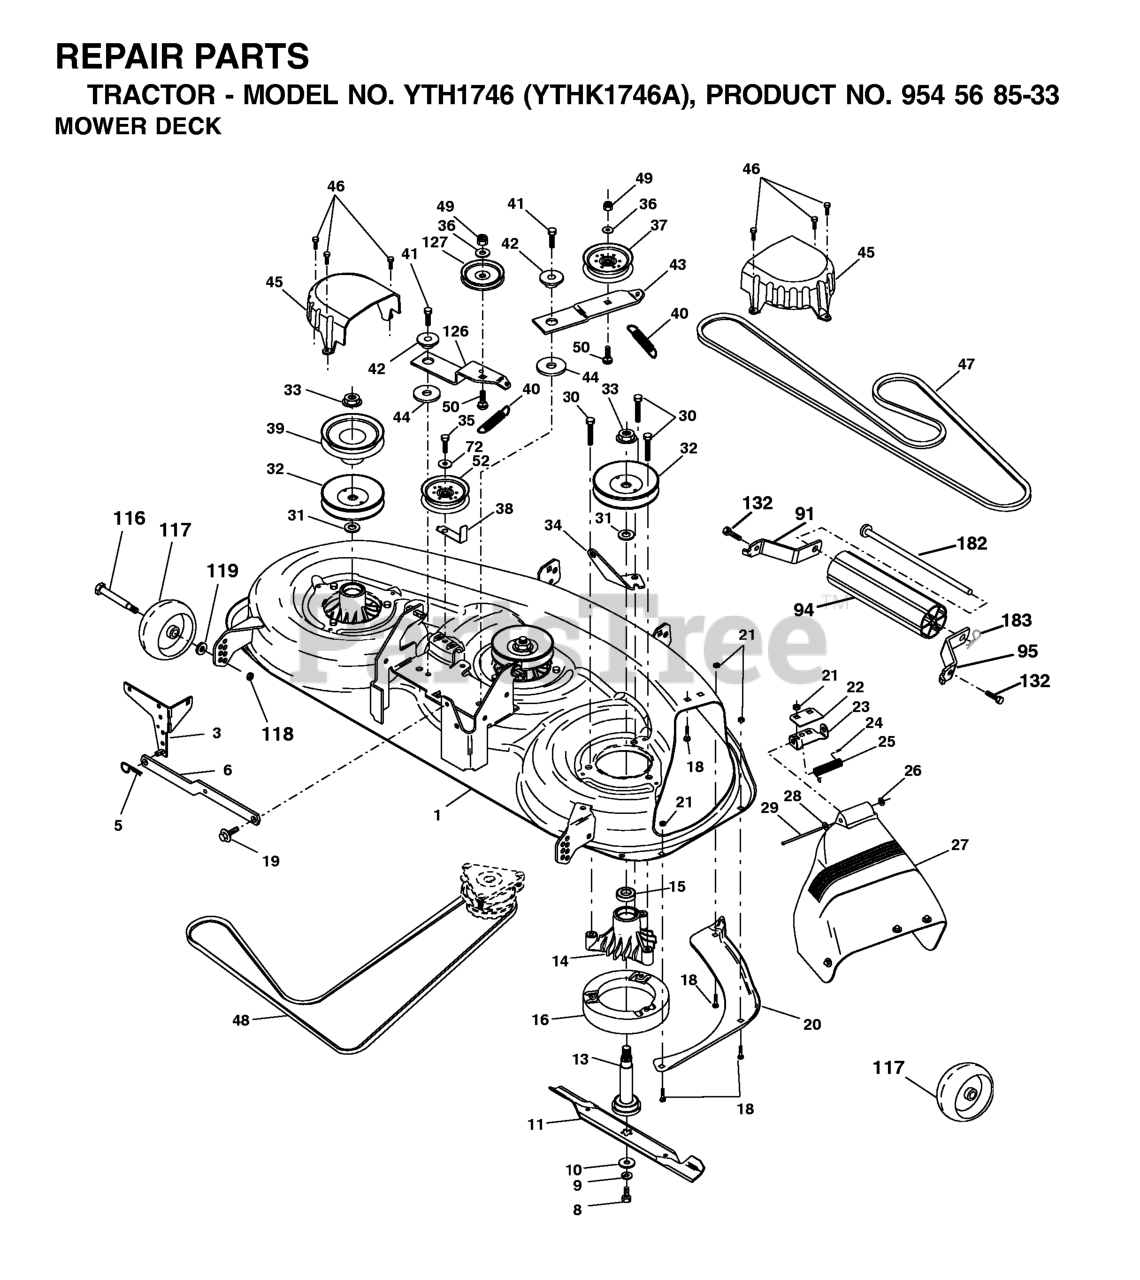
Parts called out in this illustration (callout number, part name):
3	BRACKET SWAY BAR
5	RETAINER-SPRNG RB
6	BAR SWAY DECK
8	BLADE BOLT
9	LOCKWASHER
10	WASHER.BLADE
11	BLADE.46".HI-LIFT.PREMIUM
13	SHAFT.ASM.W/BEARING
14	HOUSING.MANDREL.44/46" VENT
16	STRIPPER.MANDREL.ROUND.BLACK
18	BOLT
19	BOLT SHD 5/16-18
20	BAFFLE, VORTEX MOWER 46"
21	LOCKNUT
22	STIFFENER BRACKET
23	DEFLECTOR BRACKET
24	CAP-SLEEVE LT
25	TORSION SPRING
26	NUT PUSH M
27	DEFLECTOR
28	Washer 11/32 x 5/8 x 16 Ga SD
29	ROD.HINGE
30	SCREW, WASHER HEAD
31	WASHER
32	MANDREL PULLEY
33	NUT, FLG TOPLOCK 9/16"
34	ANCHOR, SPRING DECK 46"
35	SCREW LT
36	WASHER
37	PULLEY.IDLER.FLAT
40	SPRING.SEC.44"VEN
41	SCREW.3/8-16
42	SPACER RETAINER
43	ARM IDLER DECK 46"
44	HARDENED WASHER
45	COVER MANDREL 46
46	SCREW.1/4-20X5/8
47	BELT V SECONDARY
48	V-BELT PRIMARY 50"
50	BOLT.3/8-16X1.50
52	PULLEY.IDLER.FLAT.46".PRIMARY
72	WASHER
91	BRACKET ASM NOSEROLLER LH
94	NOSE ROLLER
95	BRACKET ASM NOSEROLLER RH
116	BOLT, SHOULDER
117	WHEEL GAGE DONUT
118	LOCKNUT
119	WASHER.5/16.FLAT.STE.STD.
126	ARM IDLER PRIM 46
132	SCREW 3/8-16X3/4
182	ROD ROLLER NOSE STANDARD
183	SPRING RETAINER
